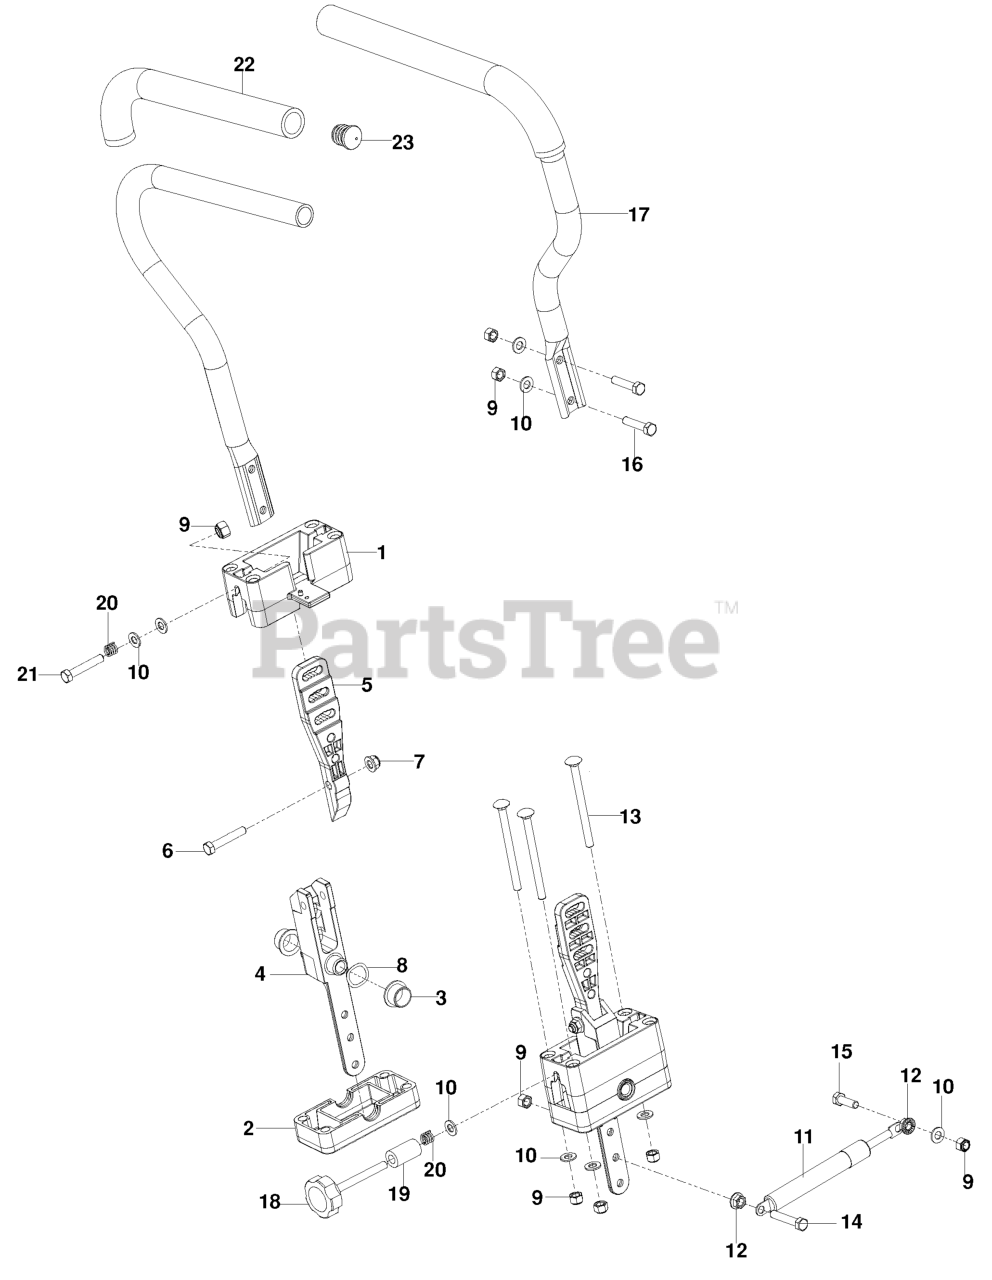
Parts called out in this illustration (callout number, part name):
1	BLOCK, UPPER
2	BLOCK, LOWER
3	BEARING, FLANGE
4	PIVOT.SECTION.DRIVE.CONTROL
5	MOUNT, DR CNTRL HANDLE
6	HCS 5/16C X 1 3/4
7	5/16-18 NYLOC FLANGE NUT
8	WASHER, .825 X 1.087, WAVE
9	NUT 5/16 NYLOC
10	FLAT WASHER 5/16 SAE
12	NUT 5/16C WHIZ
13	RHSNB 5/16-18 X 4 GR 5 ZD
14	HCS 5/16-18X1-3/4 TPBLT
15	HCS 5/16C X 1
16	CAPSCREW 5/16 X 1/1/2 HEX HEAD
17	LEVER.DRIVE.W/GRIP
21	HCS 5/16-18 X 2 TPBLT GR 5 ZD
22	GRIP, FOAM (GROUND) 15
23	END PLUG 15/16 (BLACK)
